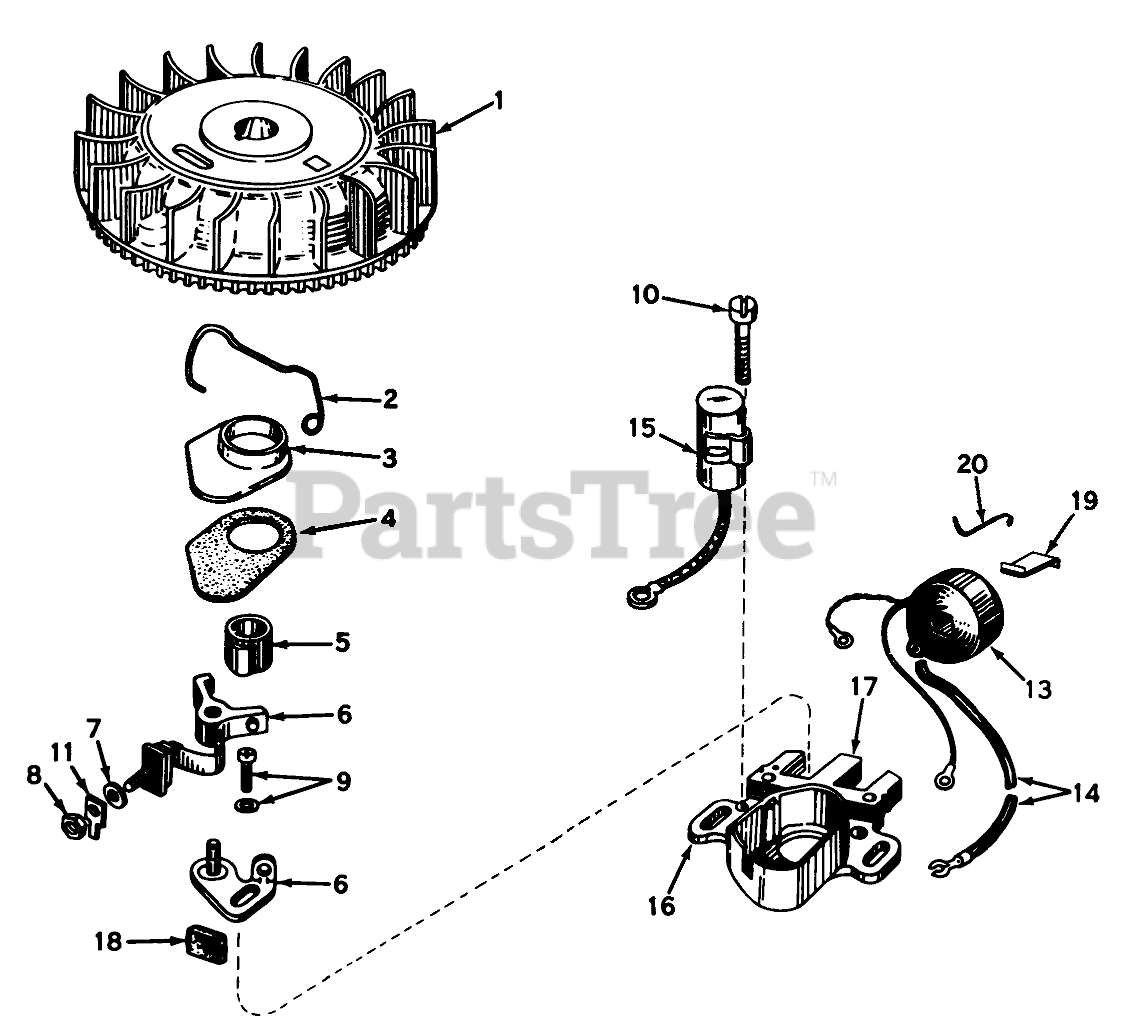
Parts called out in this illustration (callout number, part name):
1	FIywheel
2	Spring Breaker Box
3	Cover, Dust
4	Gasket Dust Cover
5	Cam, Breaker
6	Breaker Assy.
9	Breaker Screw
10	Condenser Screw
11	Terminal
13	Coil Assy (Incl. Ref. Nos. 14, 15 & 19)
14	Wire, Lead
15	Condenser
16	Core & Plate
17	Stator Assy. (Incl. Nos. 2, 3, 5 thru 14 & 16 thru 19)
18	Felt,Cam Wiper
19	Spring Coil Wedge
20	Clip, Coil
